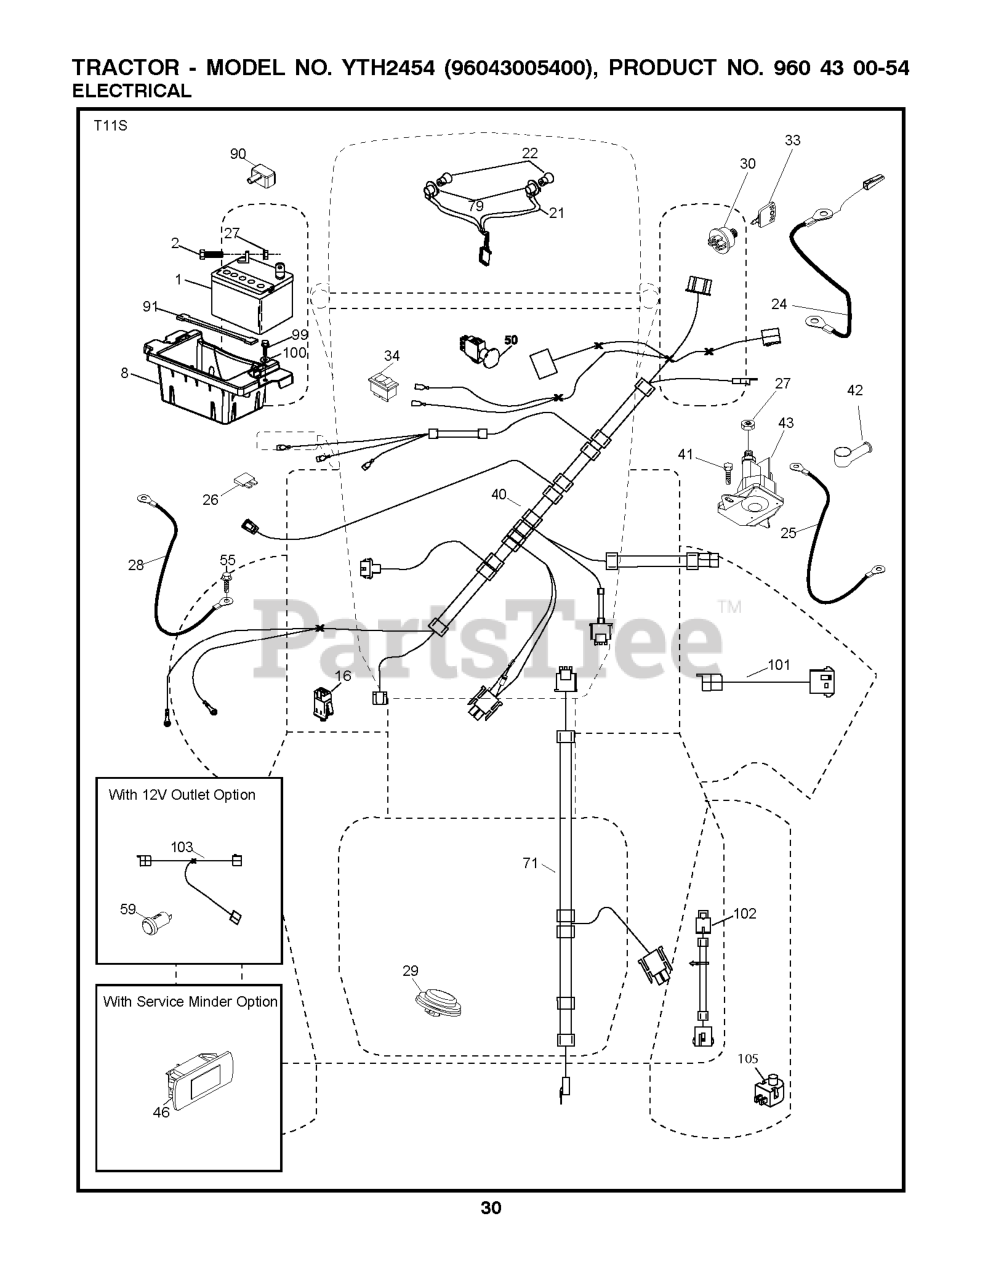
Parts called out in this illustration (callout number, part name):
1	BATTERY 12V .35 AMP
2	BOLT.HEX.1/4.X.3/4.DICHROMATE
8	BOX.BATTERY.MOUNT.FRONT.LT
16	SWITCH INTERLOOK PUSH-IN
21	HARNESS ASSY LIGHT
24	CABLE.BATT.POS.WIRE.TG.DA SOL
25	CABLE.STARTER.6G.BL/RED.17.5
26	FUSE 20AMP
27	NUT
28	CABLE GROUND 6 GA 21" 90T BLK
29	SWITCH.SEAT.DELTA.OPC.
30	SWITCH.IGN.DELTA.W.LGH.ROS
33	KEY.CHAIN.BLISTER.PACK.GEN.INT
40	HARNESS.IGN.DASH.HUQ/P
41	SCREW
42	TERMINAL COVER
43	SOLENOID.W/BRASS.PLUNGER
46	RP.GUAGE.SRVCMNDR.HRMTR.
50	RP.PTO.SWITCH.8 TERMINAL.BLACK
55	SCREW.THDROL.5/16-18X3/4.TTY
59	OUTLET.12-VOLT
71	HARNESS-CHASSIS SUB
79	BULB HOLDER ASM.
90	COVER.TERMINAL.BATTERY
91	STRAP.BATTERY.MOUNT.FRONT(2 2)
99	SCREW HEXWSHR 1/4-20X3/4
101	PIGTAIL.MATNLK.NEW.HAR
102	HARNESS PIGTAIL PCH TEX ROS
103	HARNESS PIGTAIL 12V OUTLET
105	REVERSE SWITCH
